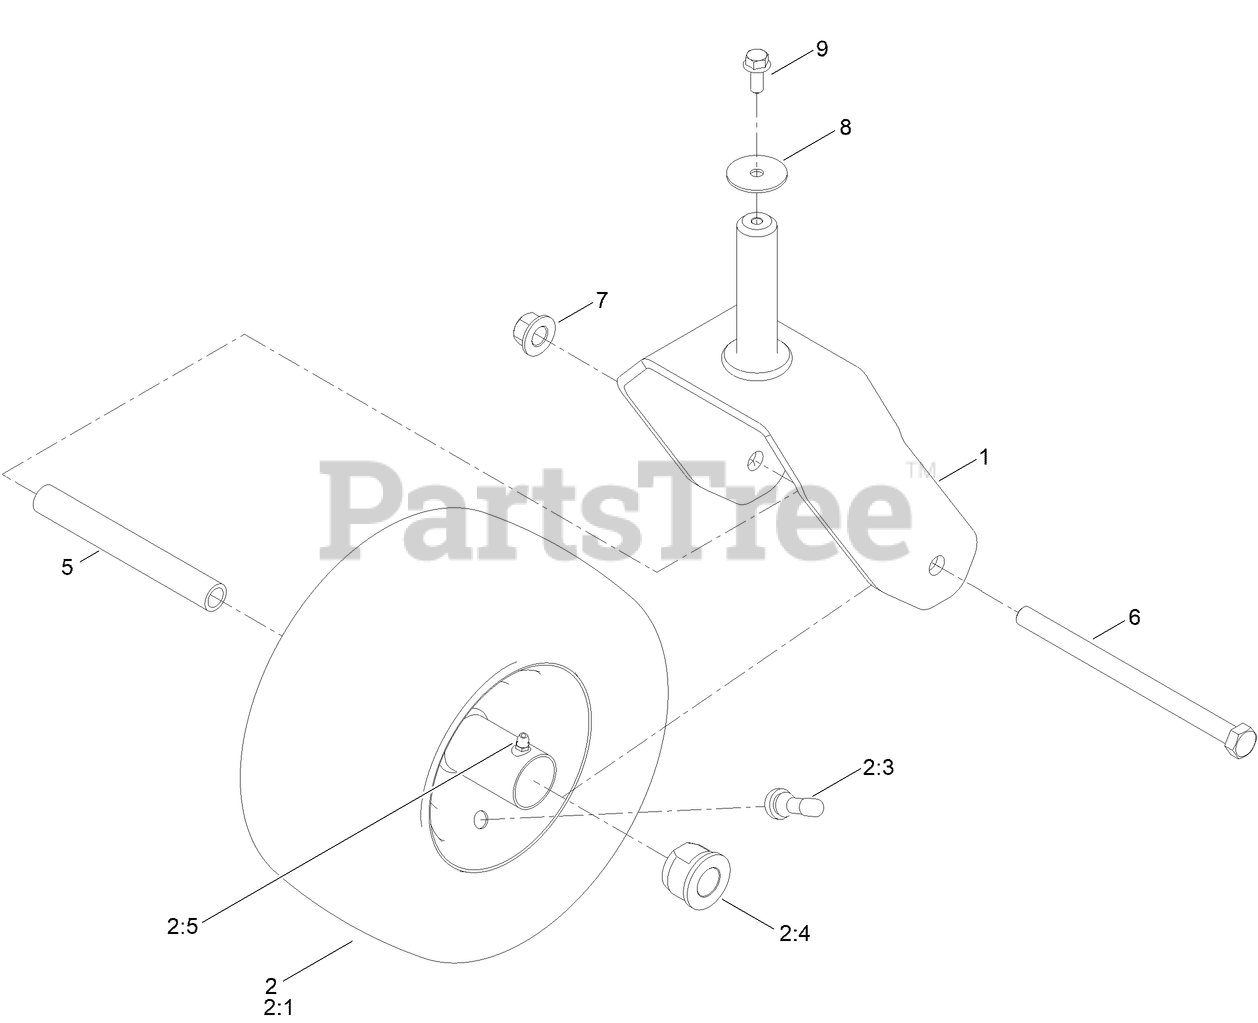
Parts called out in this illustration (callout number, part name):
1	FORK ASM
2	TIRE ASM
2:4	BUSHING-FLANGE
5	SPACER-SPANNER
6	SCREW-HH
7	NUT-HF
8	WASHER-FLAT
9	SCREW-HHF
